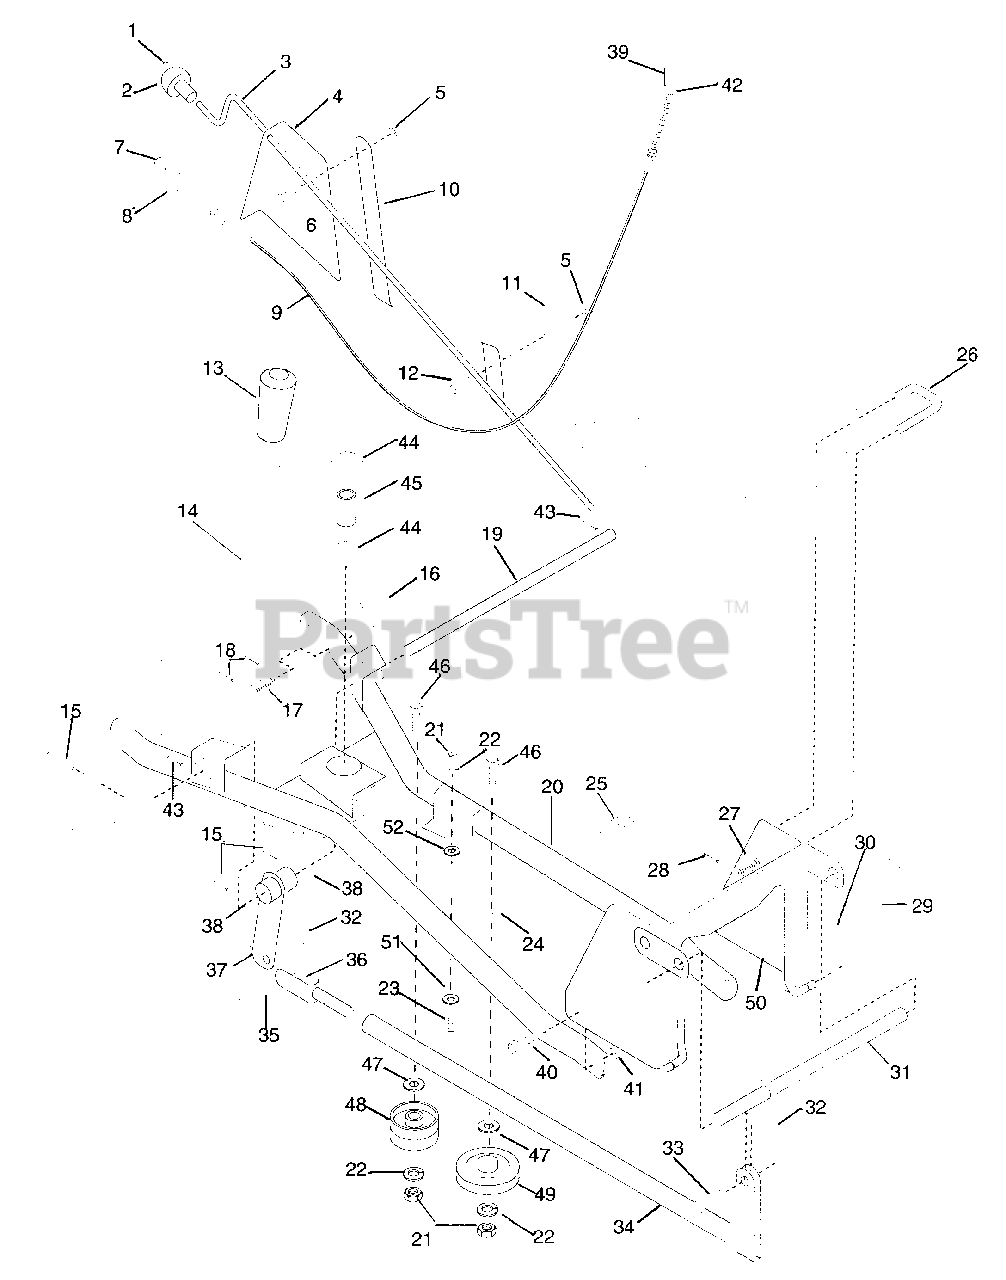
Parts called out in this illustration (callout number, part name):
1	NUT-LK-JAM-CTR .375-16 PL
3	CHUTE CONTROL CRANK
4	CONTROL BRACKET
5	NUT-LK-NYL .375-16 PL
6	BLT-RDHDSQNK .38-16X1.0 PL
7	SCR-MCH 8-32X.75 SLPAN PL
8	KNOB-BLACK
9	CONTROL CABLE
10	SUPPORT
11	PLATE, BRACE
12	BLT-HEX .38-16X1.25 PL GR5
13	GRIP,HANDLE BAR
15	PIN-GRV .250X1.50 TP A
16	LATCH PIN
17	SPRG, COMP .058X.65X2.13 WLD15
18	PIN-ROLL .125X.75
19	PIVOT ROD
20	CARRIAGE FRAME
21	NUT-HEX .375-16
22	WSHR-LK .375X.115 HVY PL
23	SHOULDER BOLT .50 X .281
24	IDLER ARM
25	SG-TENS .080X.73X3.06 WLD 20
26	LATCH PIN
27	SG-COMP .072X.77X1.75
28	PIN-ROLL .188X1.00
29	SG-GAS COMP .315X.75X10.00 120
30	PIN-HAIR INT .08X.18X1.18
31	PIVOT ROD
32	PIN-HAIR INT .14X.4X2.75
33	CLEVIS PIN
34	TUBE, LIFT
35	PIN-CLEV .494X1.25 YWZC
36	CLEVIS R.H.
37	LEVER, ACTUATOR
38	WSHR-FL-STL .754X1.125X.062 PL
39	PIN-COTR .09X.75 PL
40	BLT-HEX .62-11X1.50 PL GR2
41	NUT-LK-NYL .625-11 PL (ND)
43	PIN-COTR .12 X 1.25 PL
44	BRG-BALL .750X1.781X.61
45	SPACER .765X1.000X1.252
46	BLT-HEX .38-16X1.75 PL GR2
47	WSHR-FL-STL .390X.750X.125 PL
48	IDLER-FLAT 2.25 X .38
49	IDLER-V 3.06 X .38
50	PIVOT FRAME
51	WSHR-FL-STL .511X1.441X.125 PL
52	WSHR-THRST .507X.917X.031
